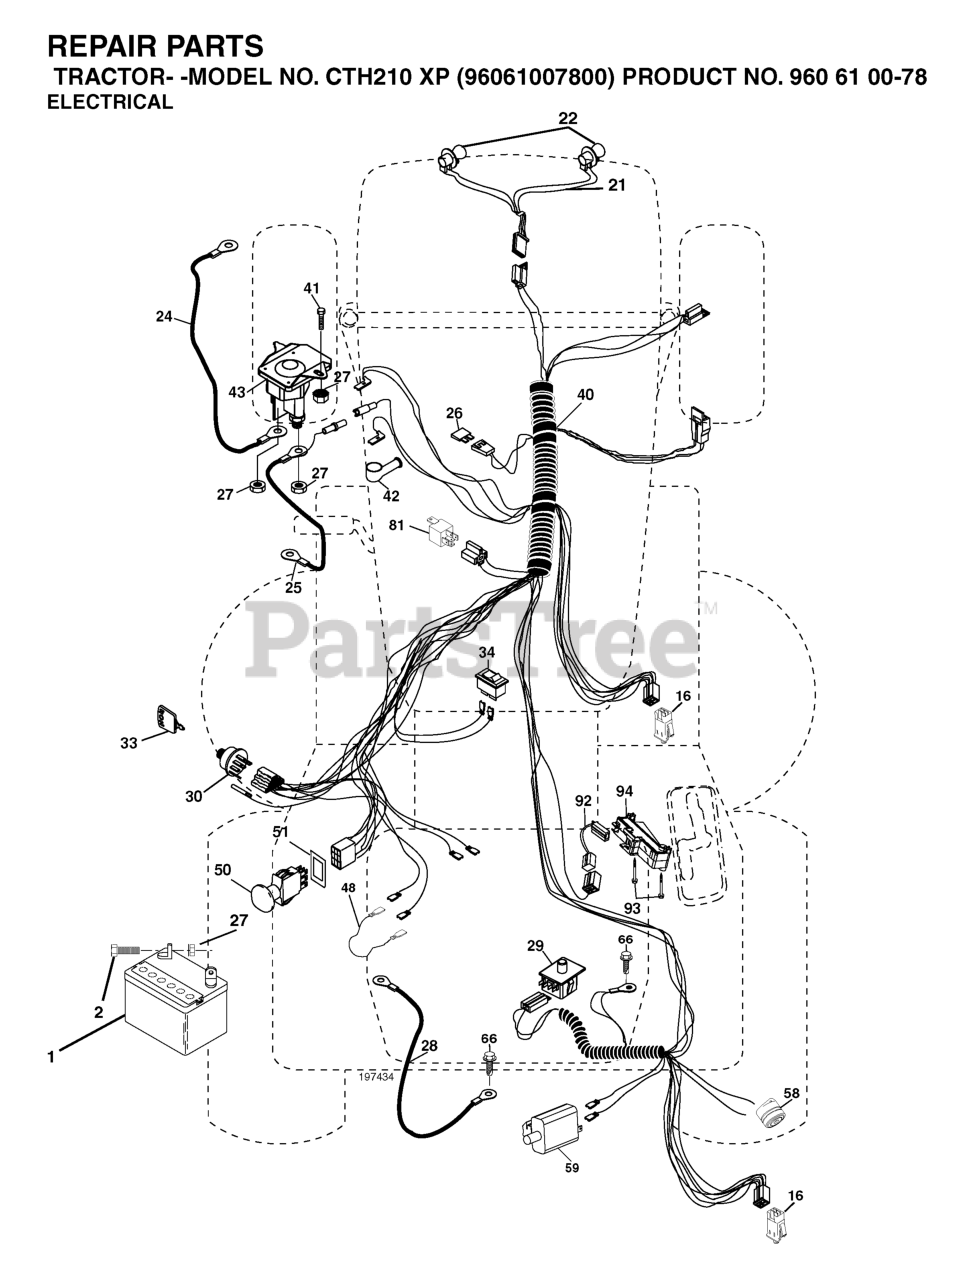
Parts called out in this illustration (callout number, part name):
1	BATTERY 12V .35 AMP
2	BOLT.HEX.1/4.X.3/4.DICHROMATE
16	SWITCH INTERLOOK PUSH-IN
21	HARNESS.W/LIGHT SOCKET
24	BATTERY CABLE GT
25	CABLE BATTERY
26	FUSE 20AMP
27	NUT
28	CABLE GROUND
29	SWITCH.SEAT.DP W/RAMPS
30	SWITCH.IGN.DELTA.W.LGH.ROS
33	KEY MLD GEN DELTA
40	RP HARNESS.IGN.ELECT.REG.CRD
41	BOLT
42	TERMINAL COVER
43	SOLENOID.W/BRASS.PLUNGER
46	GAUGE.SERVICEMINDER.HR
48	ADAPTER.AMMETER
50	RP.PTO.SWITCH.8 TERMINAL.BLACK
51	FRAME RETAINING RING
58	BUZZER
59	.WITCH.FULL BAGGER.INDICATOR
81	RELAY.ASSY.T
92	HARNESS.PIGTAIL.CONSLE
93	SCREW.PLASTITE
94	MODULE.REVERSE.ROS
